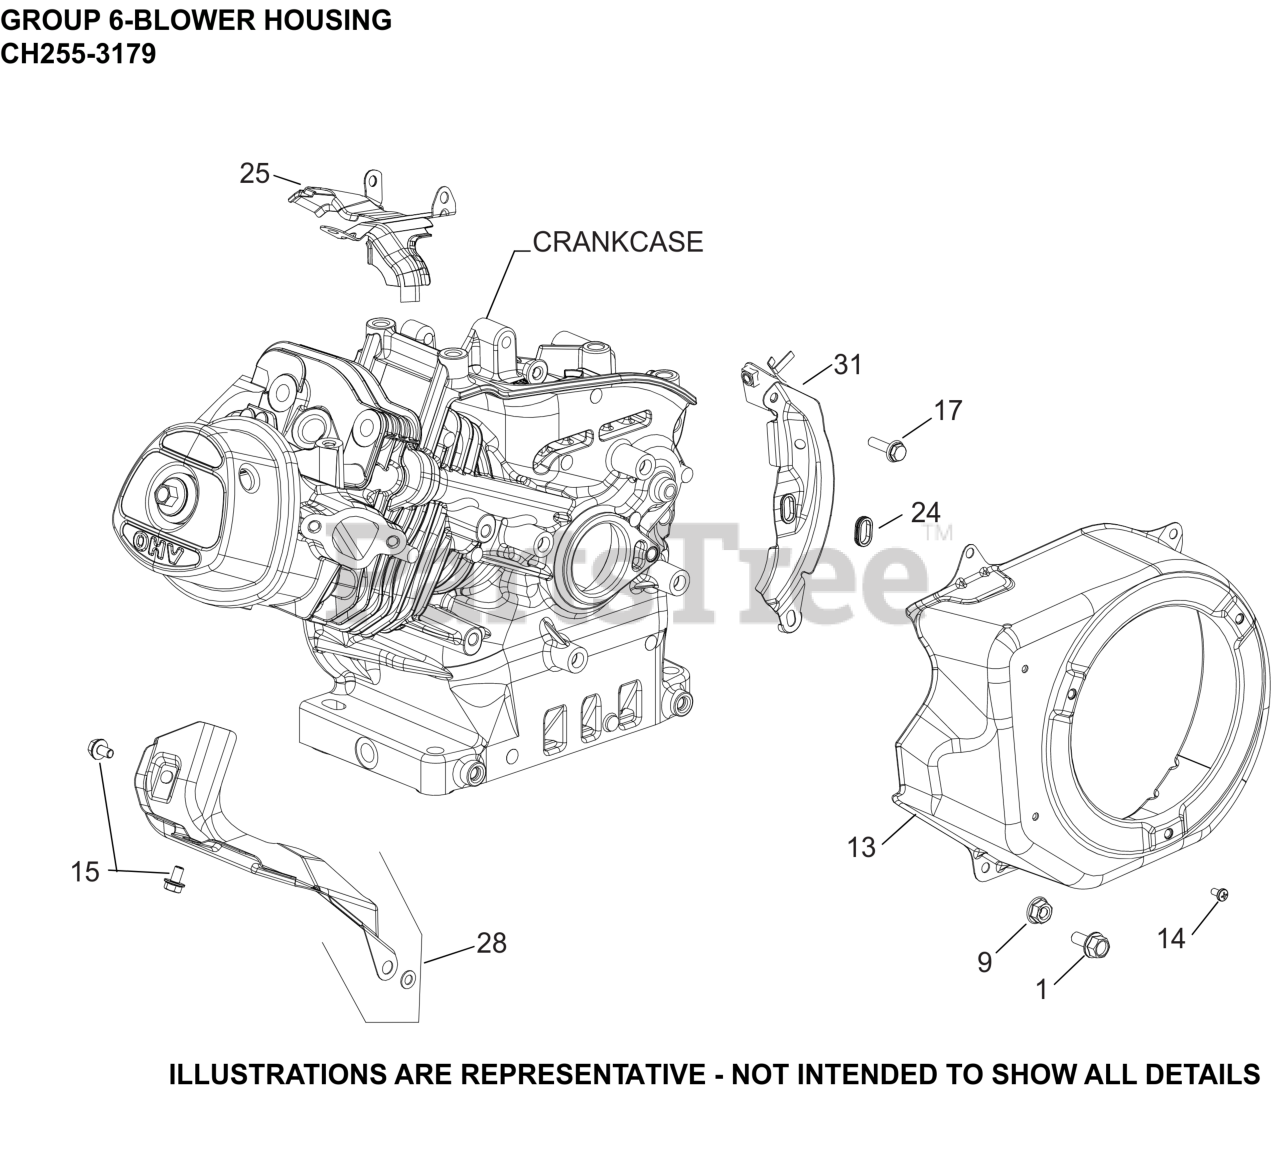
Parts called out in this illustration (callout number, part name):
1	SCREW, HEX FLANGE (M6)-USE 25 086 433-S
9	NUT, HEX FLANGE (M6) - USE 14 100 16-S
13	KIT, BLOWER HOUSING
14	SCREW, COVER TO BLOWER HOUSING
15	SCREW, HEX FLANGE (M6)
17	SCREW, M6 X 22
24	GROMMET, SHIELD FLYWHEEL
25	FLOW SHIELD
28	KIT, CYLINDER SHIELD
31	SHIELD, FLYWHEEL ASSY
